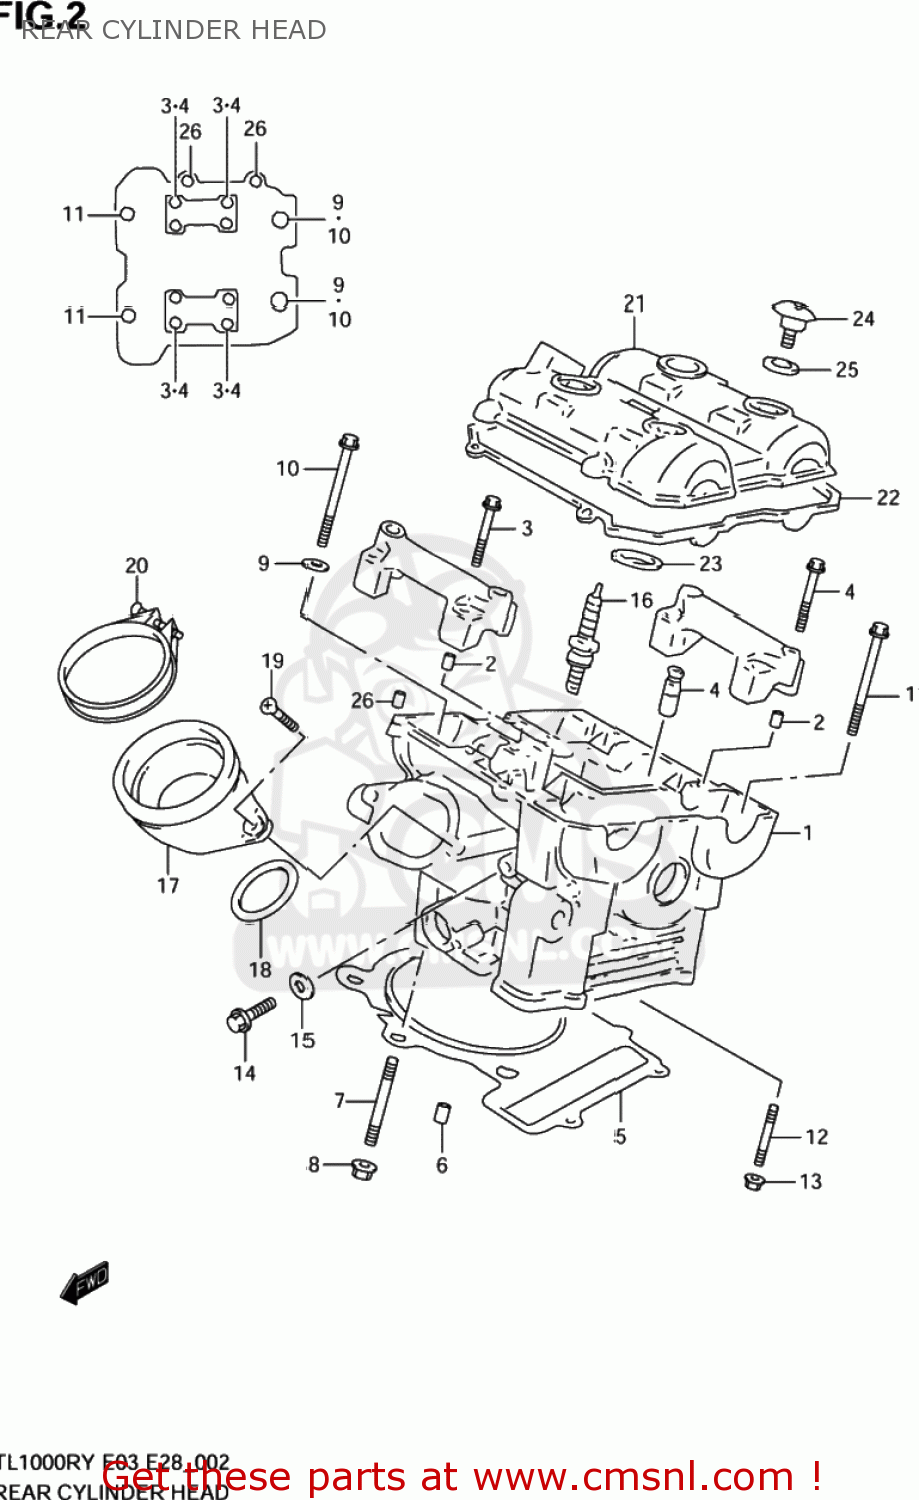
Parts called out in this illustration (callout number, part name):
1	HEAD ASSY,CYLINDER
2	PIN(6.2X8X11)
3	BOLT(6X39)
4	GUIDE,VALVE
5	GASKET,CYLINDER HEAD (NAS)
6	PIN
7	BOLT,STUD
8	NUT
9	WASHER(10.5X19X2)
10	BOLT,CYLINDER HEAD(L:175)
11	BOLT(6X70)
12	BOLT,STUD
13	NUT
14	BOLT
15	GASKET(5.8X13X1.2) (NAS)
16	PLUG,SPARK(CR9EK)
17	PIPE ASSY,INTAKE
18	O RING(D:2.4,ID:55.6)
19	SCREW
20	CLAMP
21	COVER,CYLINDER HEAD RR
22	GASKET,CYL HEAD COVER NO.1 (NAS)
23	GASKET,CYL HEAD COVER NO.2
24	BOLT(7X17.5)
25	WASHER(10.6X25.5X2.3)
26	PIN(6.2X8X11)
